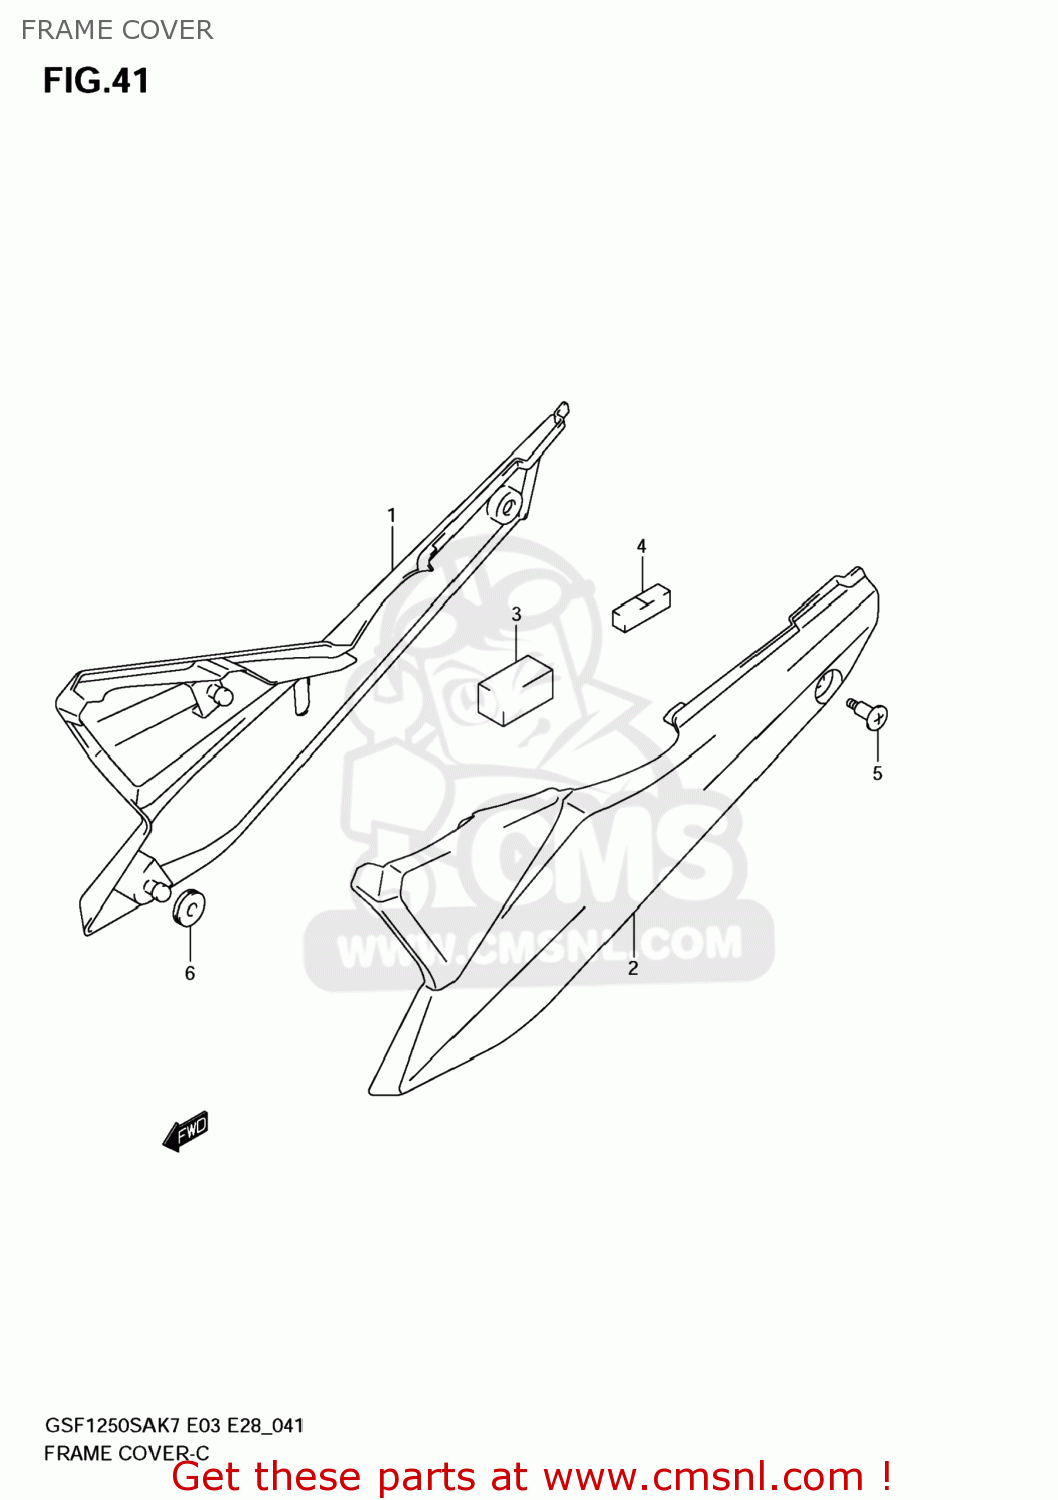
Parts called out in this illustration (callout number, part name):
1	COVER,FRAME,R(BLACK)
2	COVER,FRAME,L(BLACK)
3	RUBBER
4	CUSHION
5	SCREW,FUEL TAN
6	CUSHION
